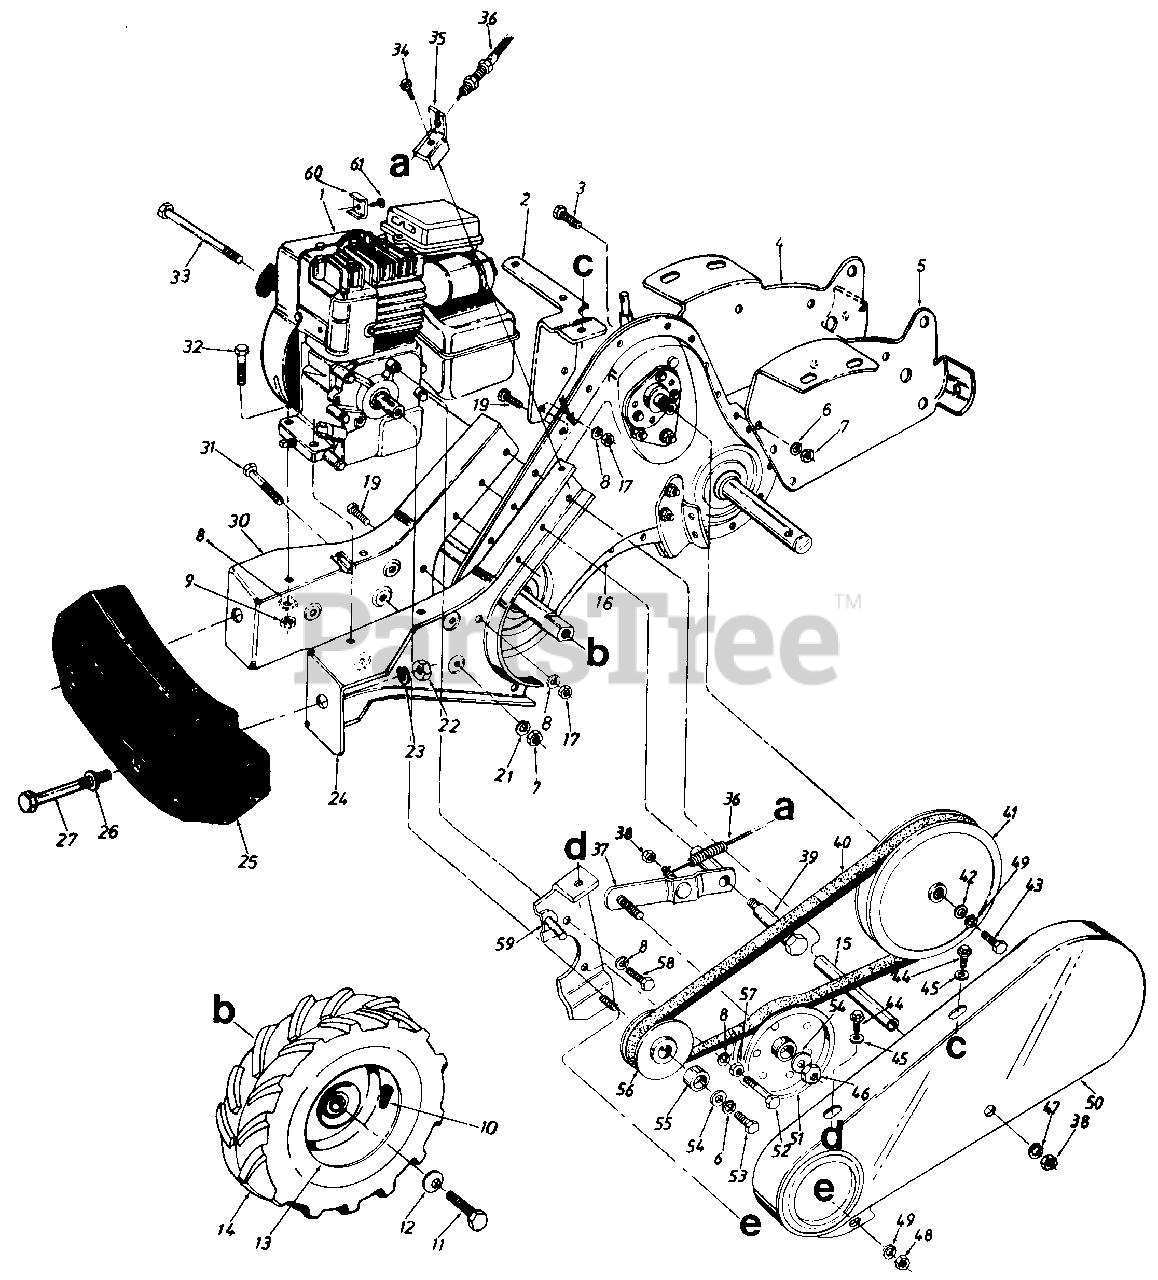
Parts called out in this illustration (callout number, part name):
1	Engine
4	Tine Shield Mtg. Brkt.-R.H.
7	Hex Nut 3/8-16 Thd.
8	L-Wash. 5/16" I.D.
9	Hex Nut 5/16-18" Thd.
10	Air Valve
11	Hex Bolt 5/16-24 x .62" Lg.
12	Bell-Wash. .345" I.D. x .88"
13	Wheel Rim Ass'y. Only
14	L.H. Wheel Ass'y. Comp.
14	R.H. Wheel Ass'y. Comp.
14	Tire Only 13 x 5.0
15	Spacer 3/8" I.D. x 3.38" Lg.
16	Transmission Comp.
17	Hex Nut 5/16-18 Thd.
19	Hex Bolt 5/16-18 x .75" Lg.
21	L-Wash. 3/8" I.D.-H.D.
22	Hex Nut 1/2-13 Thd.
23	L-Wash. 1/2" I.D.*
26	Fl-Wash. .510" I.D. x 1.0"
27	Hex Bolt 1/2-13 x 5.00" Lg.
32	Hex Bolt 5/16-18 x 1.50"*
33	Hex Bolt 5/16-18 x 4.75" Lg.-Gr. 2
34	Hex Wash. TT-Tap Scr. 5/16-18 x .62" Lg.
35	Bracket Clutch Cable
36	Clutch Control Cable 53" Lg.
39	Shld. Bolt .500" Dia. x 2.27"
40	V-Belt
41	V-Pulley Split 518" I.D.
42	Fl-Wash. 1/4n l.D. x .93" O.D.
43	Hex Bolt 1/4-28 x .75" Lg.
44	Hex Wash. Hd. S-Tap Scr. 1/4-20 x .50" Lg.
45	Fl-Wash. .281" I.D. x .625"
46	Hex Cent. L-Nut 3/8-24 Thd.
47	Fl-Wash. 5116" I.D.
48	Hex Nut 1/4-20 Thd.*
49	L-Wash. 1/4" I.D.*
51	Fl-ldler w/Flanges 3.75" O.D.
52	Hex Bolt 5/16-24 x 1.75"*
53	Hex Bolt 3/8-24 x 1.00" Lg.*
54	Fl-Wash. 3/8" l.D. x 1.00"
55	Spacer .758" l.D. x 990"
56	Engine Pulley
57	Hex Nut 5/16-24 Thd.*
58	Hex Bolt 5/16-24 x .62" Lg.*
61	Hex Sems Scr. #10-32 x .62"
